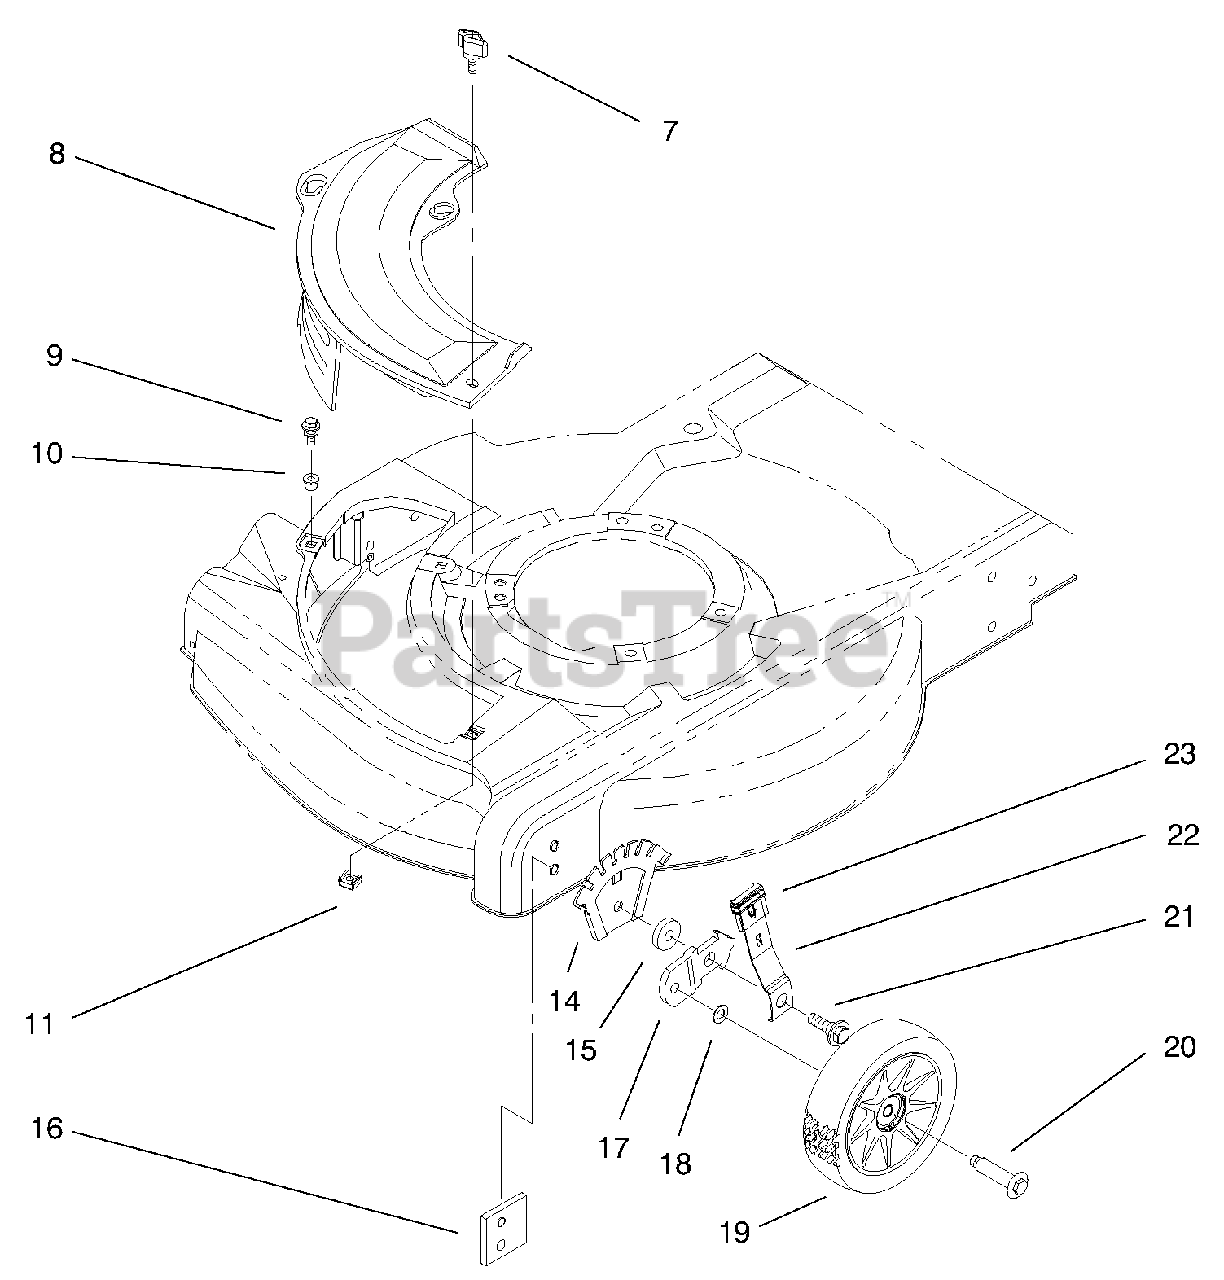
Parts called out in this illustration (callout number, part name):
7	Knob-Cover Plate
8	Mulch Plate-21"
9	Screw-Sems
10	Grommet-Plastic
11	Nut-Cage
14	Plate-Height Adjust
16	Plate-Baffle
17	Bracket-Wheel Height Adj
19	ASM-Wheel & Tire 6"
20	Bolt-Shoulder
21	Bolt-Shoulder
22	Spring Arm-Front
23	Knob-Height Adjust
